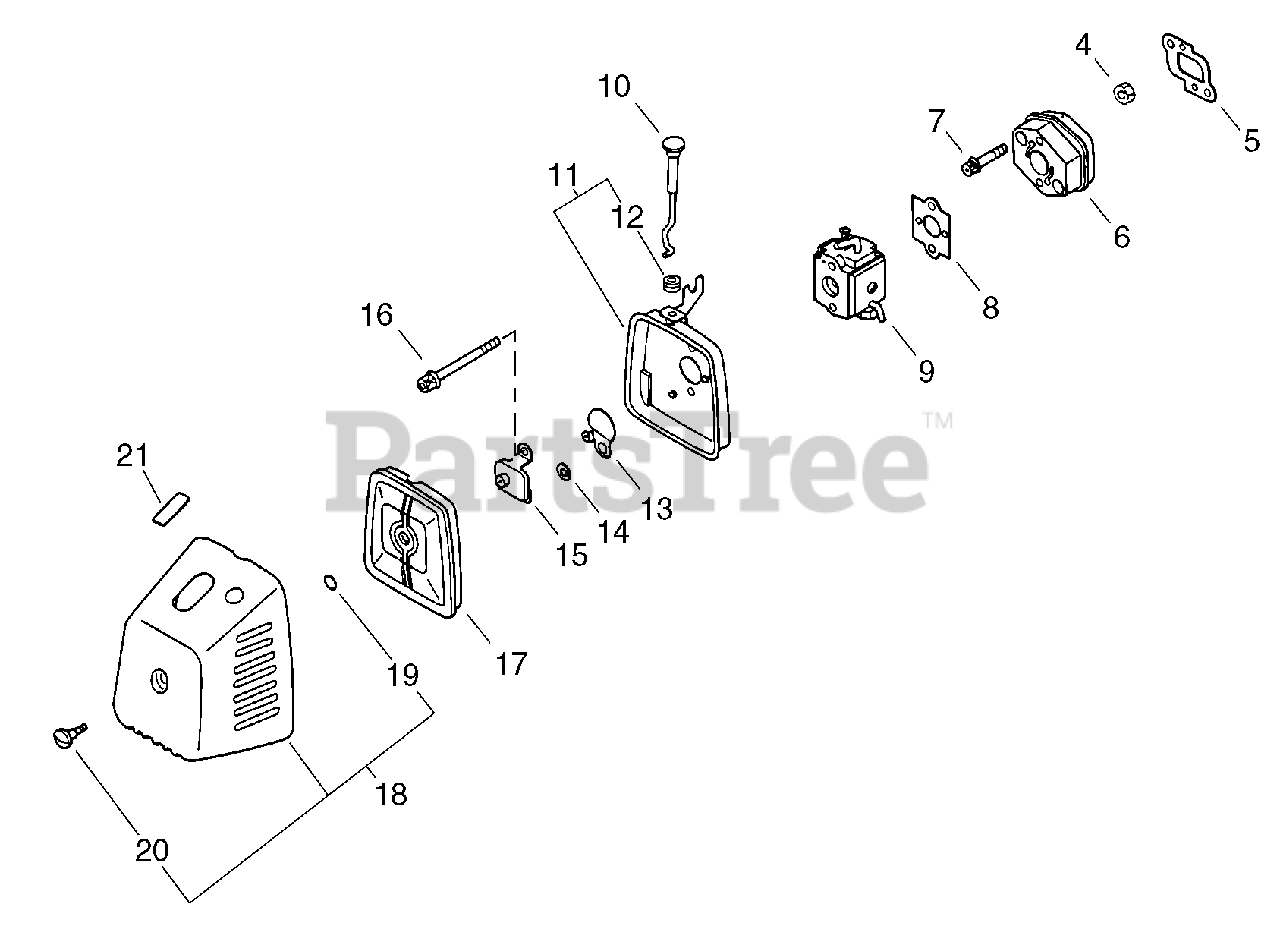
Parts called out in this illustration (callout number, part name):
4	NUT M5
5	GASKET, INTAKE
6	INSULATOR, INTAKE
7	BOLT 5×25
8	GASKET, CARBURETOR
10	ROD, CHOKE
11	CASE ASSY, AIR FILTER
12	GROMMET, CHOKE
13	SHUTTER, CHOKE
14	WASHER 5.2×8×0.8T
16	SCREW 5×57
17	FILTER, AIR
18	COVER ASSY, AIR FILTER
21	LABEL, CHOKE
